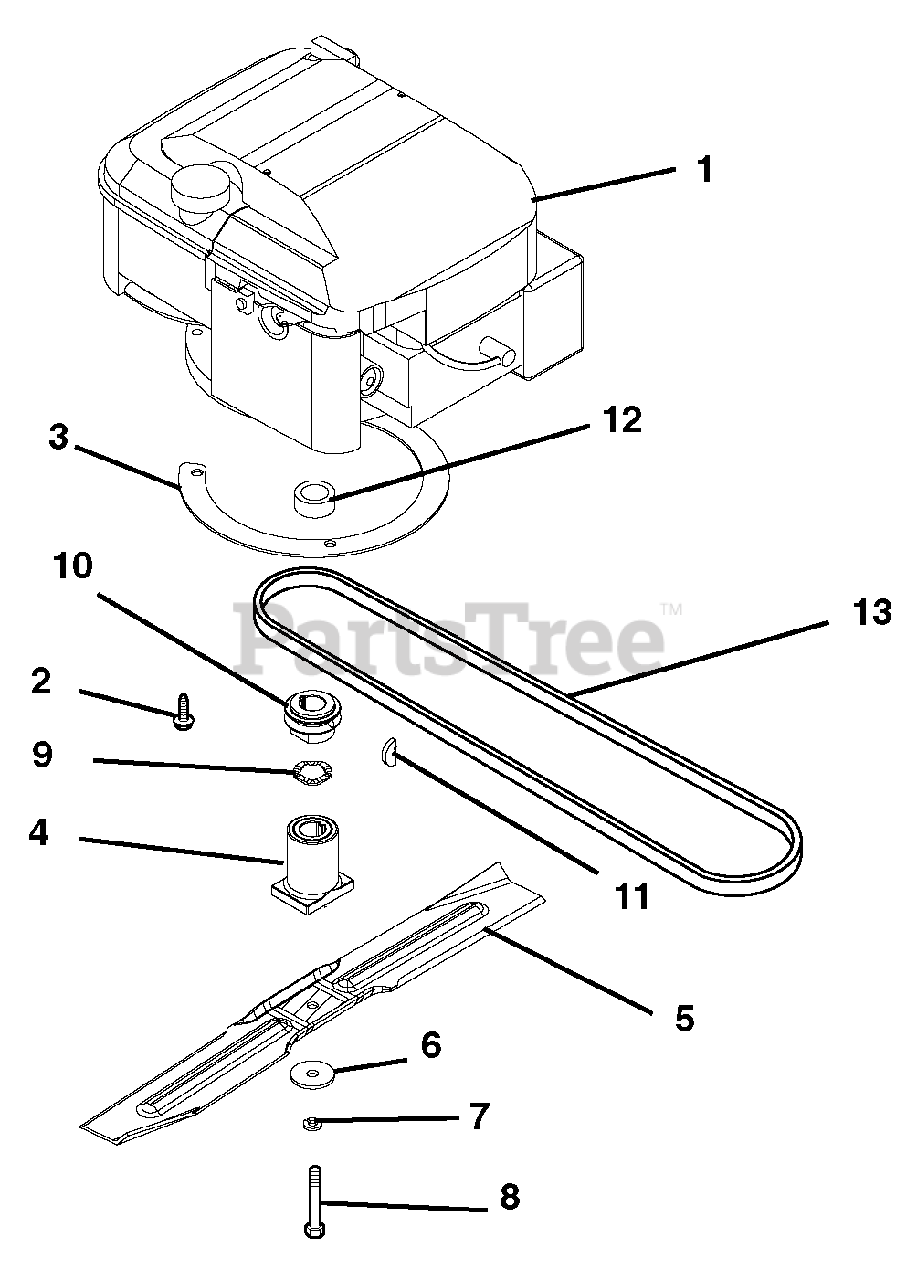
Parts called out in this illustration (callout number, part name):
1	Engine, Briggs and Stratton Quantum 6.5 hp (Briggs Engine Model # - 123K02)
1	Engine, Honda GCV 160 5.5 hp (Honda Engine Model # - GCV160A)
1	Engine, Honda GCV 160 5.5 hp, Electric Start (Honda Engine Model # - GCV160A)
2	Screw-Tapping .38-16X1.00 Hex Washer Head
3	Ring, Engine Bolt
4	Adapter, Blade Hub
5	21" Mower Blade
6	Washer, Flat Steel .39 x 1.5 x .125
7	Washer, Locking .38 x .094 Regular
8	Bolt, .38-24 x 2.5 Grade 8
8	Bolt, Hex .38-24 x 2.00 Grade 8
9	Washer, Wave .885 x 1.311 x .125
9	Washer, Wave 1.09 x 1.37 x .016
10	Pulley-Sintered Iron LM
10	Pulley, 1" Crank Drive
11	Key, Woodruff .156 x .625 x .25
11	Key, Woodruff .188 x.625 x .25
12	Spacer, .875 x 1.125 x .551
12	Spacer, Honda Electric Start Crank
13	V-Belt, 3L-Wrapped Clutching Belt
